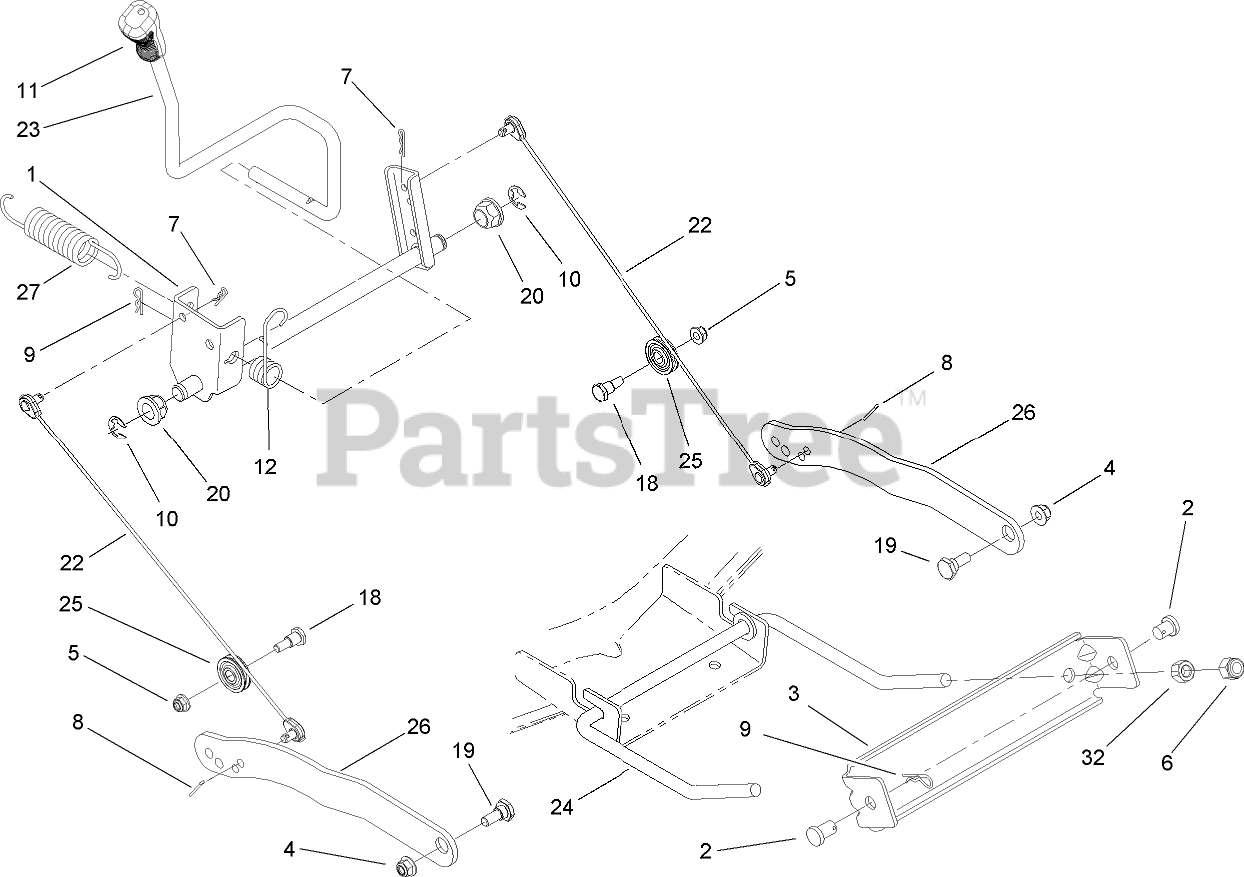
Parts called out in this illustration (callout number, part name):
1	LIFT SHAFT ASM
2	PIN-BRACKET, LIFT
3	BRACKET-STABILIZER
4	NUT-LOCK, FLANGE
5	NUT-LOCK, FLANGE
6	NUT-LOCK, HEX (NYLON)
7	PIN-COTTER
8	PIN-COTTER
9	PIN-HAIR
10	RING-E
11	GRIP-HANDLE
12	SPRING-TORSION
18	BOLT-SHOULDER
19	BOLT-SHOULDER
20	BEARING-FLANGE
22	CABLE-LIFT
23	HANDLE-LIFT
24	ROD-FRONT, ADJUST
25	PULLEY-ROLLER
26	LINK-DECK, LIFT
27	SPRING-LIFT, ASSIST
32	NUT-HEX
